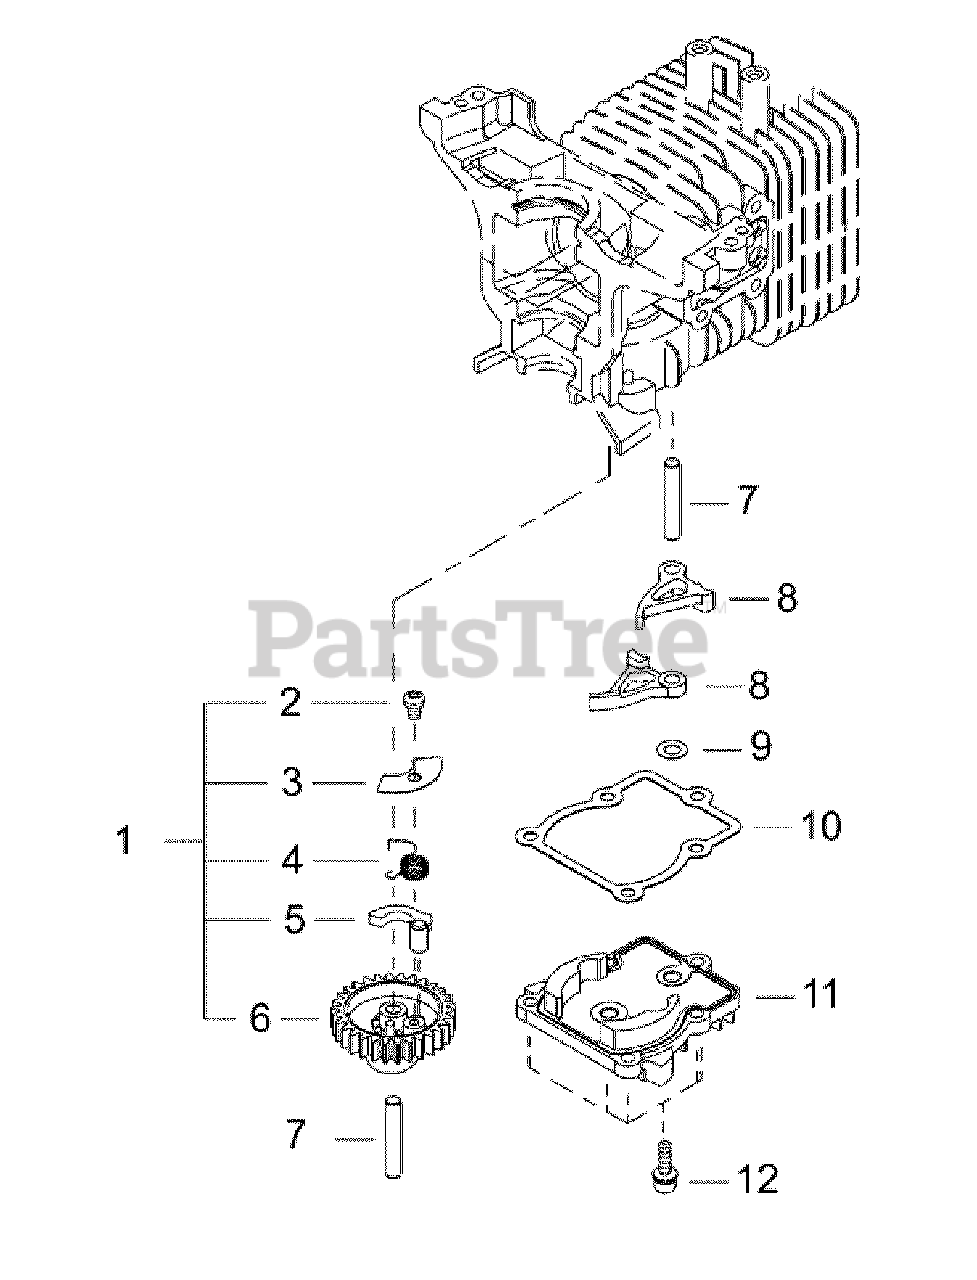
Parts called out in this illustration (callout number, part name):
1	CAM GEAR ASSY
2	SCREW - 4X6 -- TAPPING
3	COVER, PLATE
4	SPRING
5	WEIGHT
6	GEAR, CAM
7	PIN - LOCATING
8	FOLLOWER, CAM
9	WASHER - 5
10	GASKET
11	COVER, CAM GEAR
12	SCREW - 4X14
